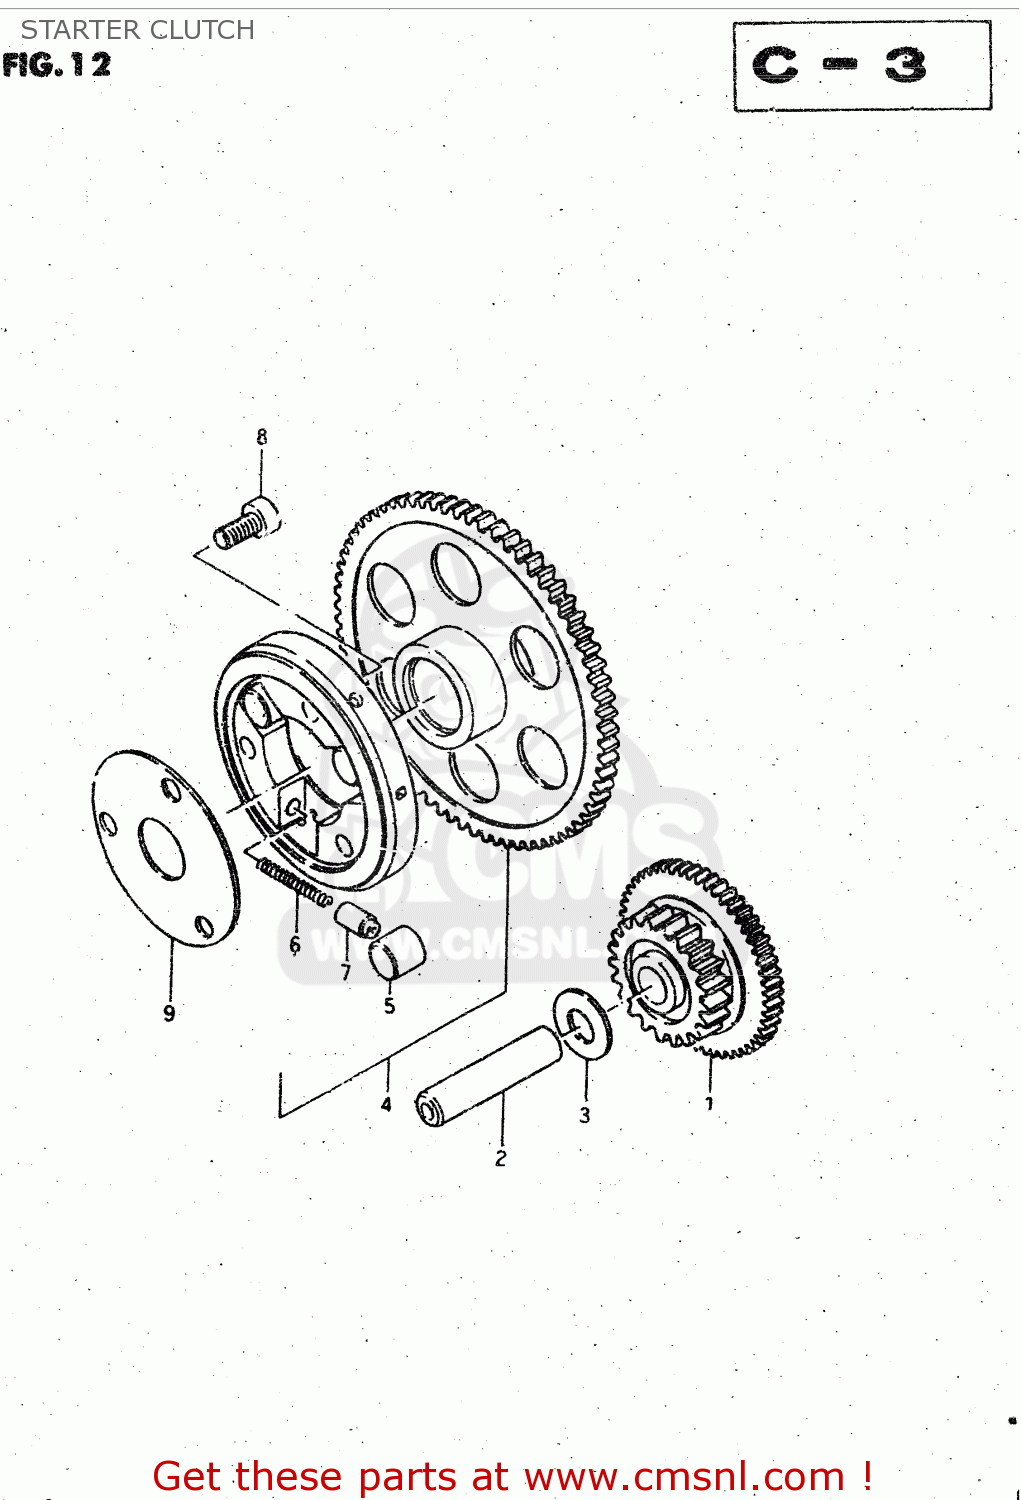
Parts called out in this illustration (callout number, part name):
1	GEAR,STARTER IDLE
2	PIN(7.4X13X56)
3	WASHER
4	CLUTCH SET,STARTER
5	ROLLER(15X13)
6	SPRING
7	PIECE,PUSH
8	BOLT
9	SHIM,STARTER CLUTCH HUB
